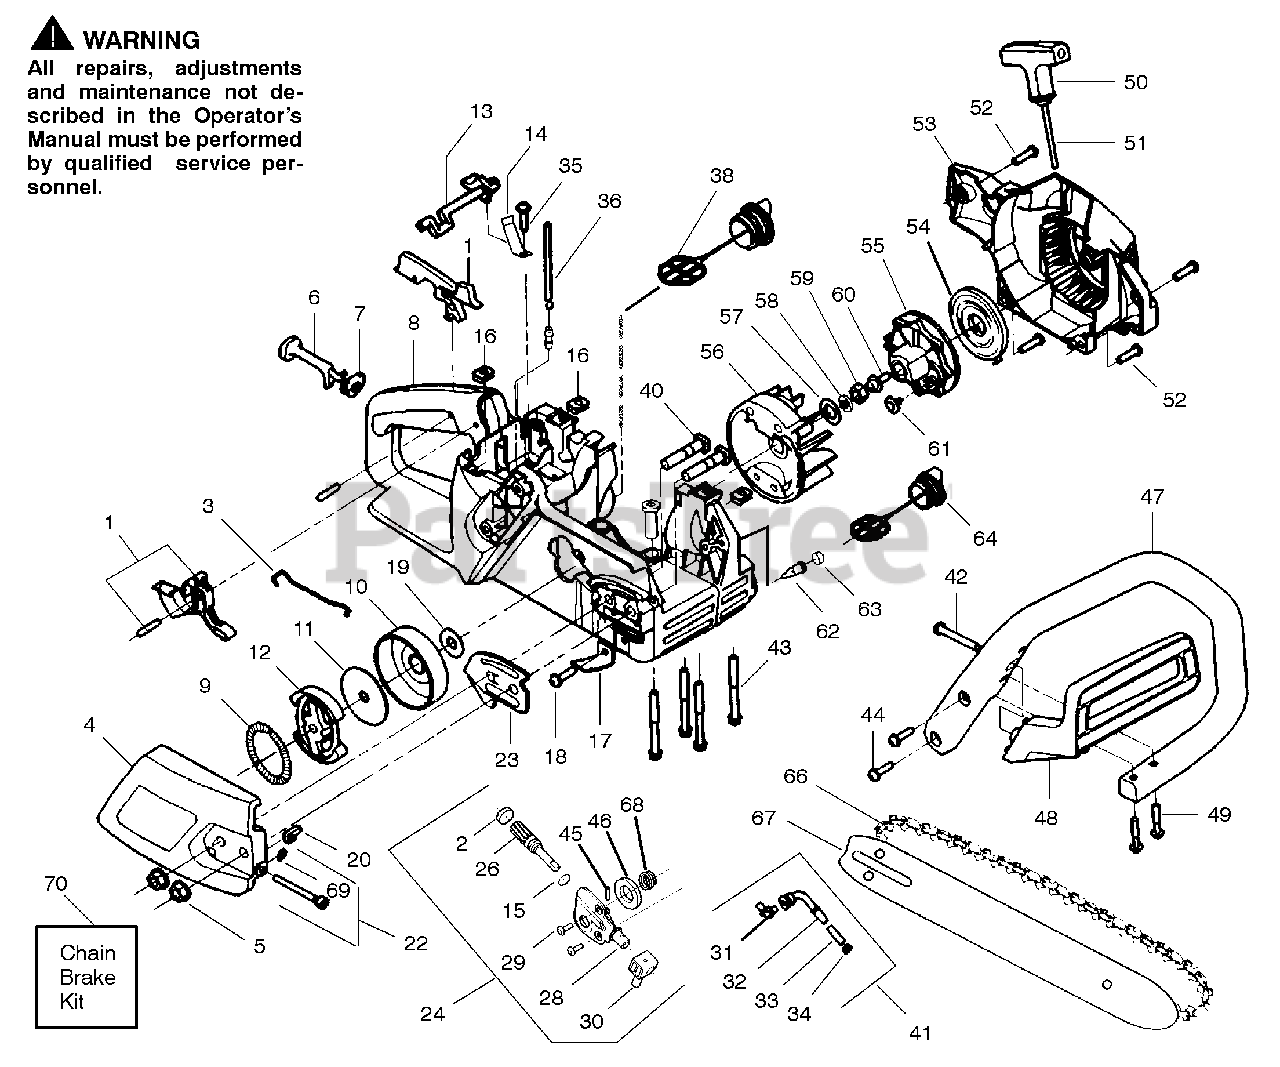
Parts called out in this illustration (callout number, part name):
1	Trigger & Lockout Kit
2	Dust Plug-
3	Wire - Throttle
4	Clutch Cover
5	Nut - Bar Mounting
6	Choke Lever
8	Chassis Ass'y.
9	Clutch Spring
10	Clutch Drum Ass'y - w/Brg.
11	Washer - Clutch
12	Clutch Ass'y.
13	Switch Lever
14	Switch Spring
15	O-Ring Oiler
17	Chain Catcher
18	Screw
19	Washer - Thrust
20	Pin -Bar Adjusting
22	Bar Adjusting Kit
23	Bar Mounting Plate
24	Oil Pump Kit-
26	Gear Ass'y.-
28	Oil Pump Body-
30	Seal Block
31	Fitting - Elbow
32	Pick-Up Tube
33	Oil Filter
34	Plug- Oil Filter
36	Fuel Line Kit (Large Dia.)
38	Fuel Cap Ass'y. w/Retainer
40	Bolt - Bar
41	Oil-Pickup Ass'y.
44	Screw
45	Pin - Dowel
46	Dust Seal
47	Front Handle
48	Handguard
50	Starter Handle
51	Rope Kit
53	Fan Housing
54	Recoil Spring
55	Starter Pulley
56	Flywheel Ass'y.
58	Lockwasher
62	Check Valve
63	Plug - Oil Vent
64	Oil Cap Ass'y.
66	Chain-14"
67	Bar-14"
68	Worm Gear Spring
69	Retainer-Bar Adjust
70	Chain Brake Kit
